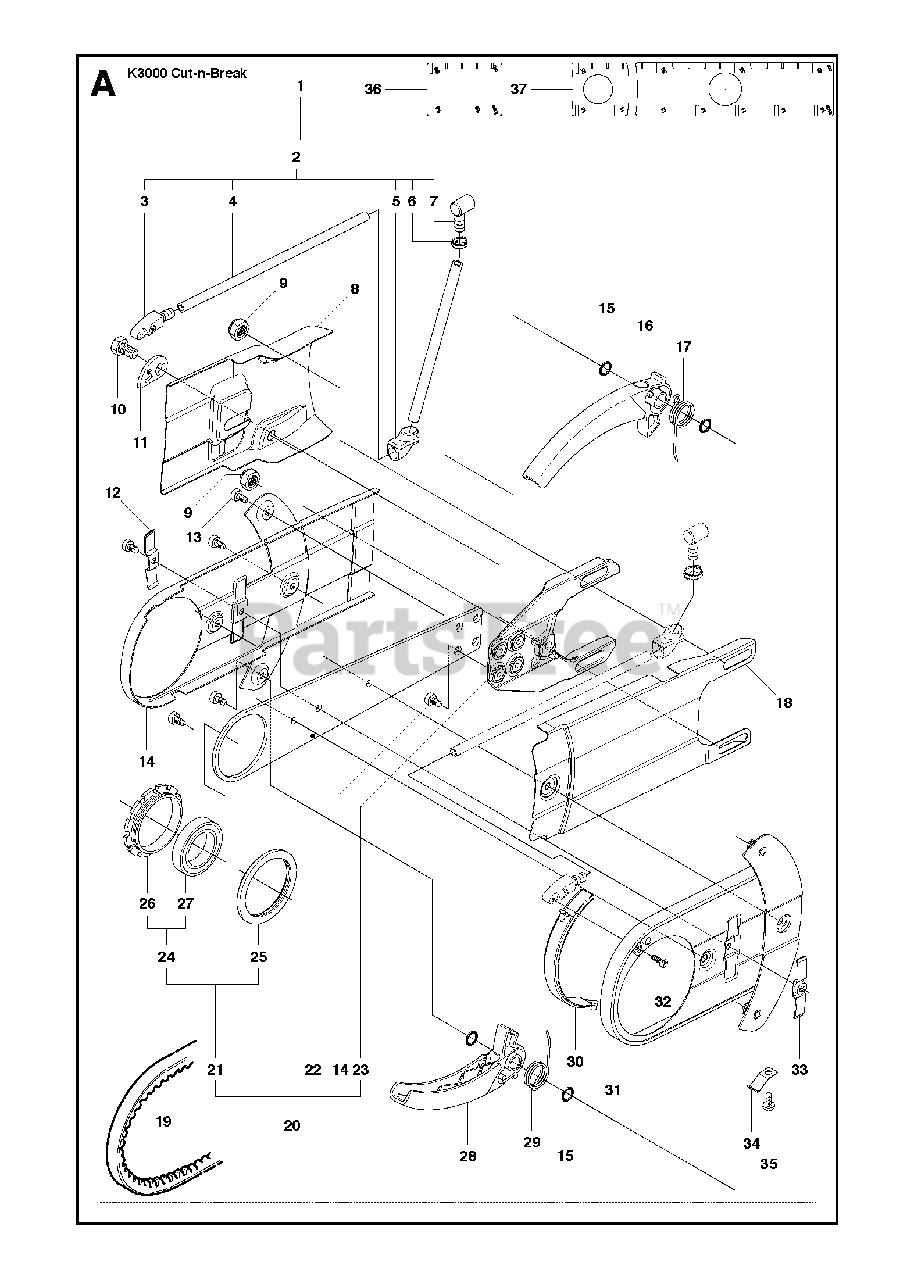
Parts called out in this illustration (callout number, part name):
4	HOSE
9	HEXAGON NUT
12	DEFLECTION LIMITER
13	SCREW ITXSCM
24	BEARING CAGE
26	BEARING CAGE
32	SCREW CCRPANT
33	DEFLECTION LIMITER
35	SCREW CRPANM
